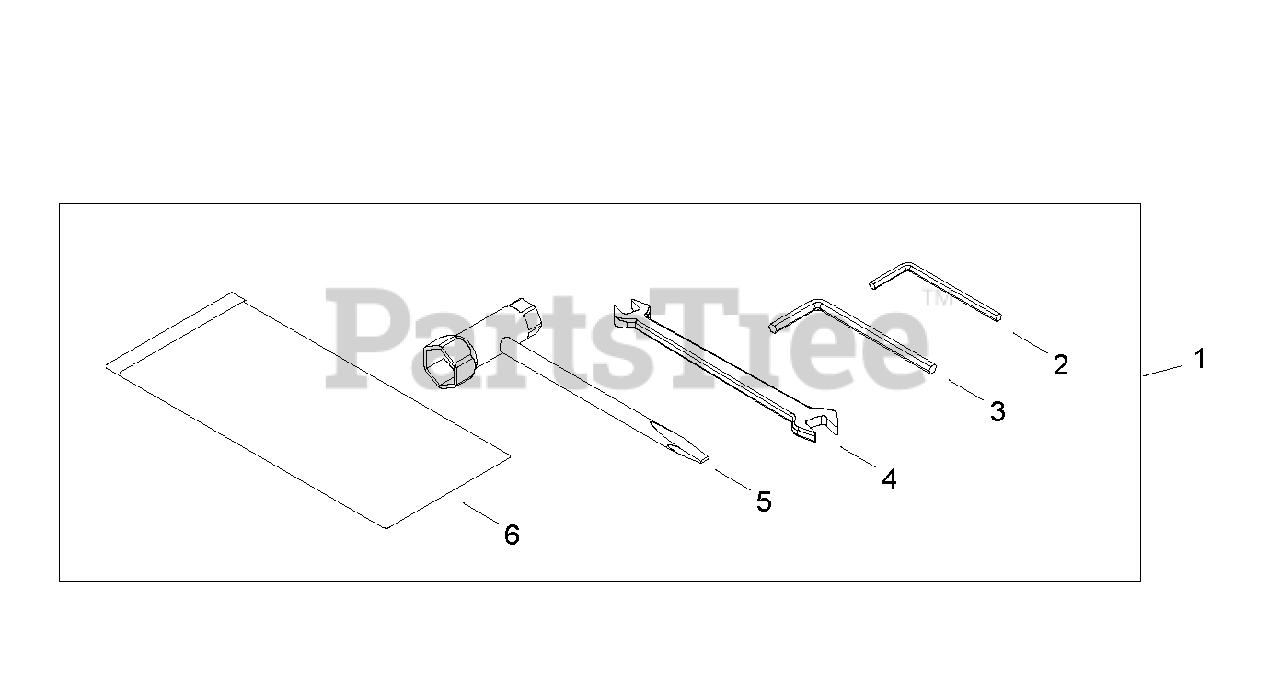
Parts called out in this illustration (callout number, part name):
1	TOOL KIT, SERVICE
2	WRENCH, ALLEN 4 MM
3	WRENCH, ALLEN 5 MM
4	SPANNER 8×10
5	T-WRENCH 16×13
6	BAG, TOOL
